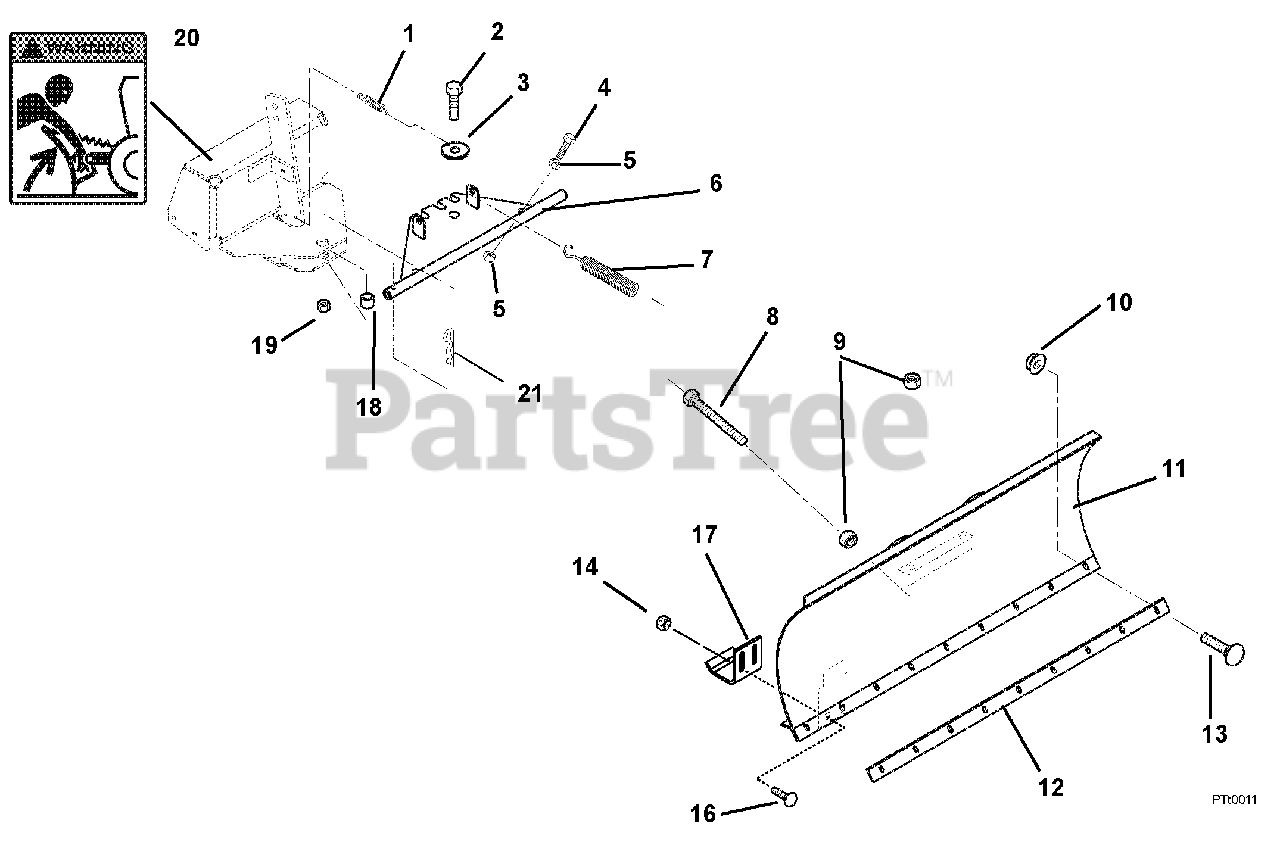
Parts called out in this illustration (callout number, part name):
1	SPRING,LATCH
2	BLT-HEX .75-10X3.00 GR5 YWZC
3	WSHR, SPECIAL
4	@BLT-HEX .50-13X2.00 GR5 YWZC
5	@NUT-HEX .50-13 YWZC
6	WMT,PIVOT PLATE
7	SPRING,BLADE ADJUSTMENT
8	BLT,HEX 3/8-16X4.00 FULL TH'D
9	@NUT-HEX .38-16 YWZC
10	@NUT-LK-TOP-FLG .31-18 YWZC
11	DOZER BLADE, 54" WELDMENT 12GA
12	SCRAPER BLADE, 54" DOZER BLADE
13	@BLT-RDHDSQNK .31-18X.75 G5YZ
14	@NUT-LK-CTR .38-16 YWZC
16	@BLT-RDHDSHSQNK.38-16X1.0 G5YZ
17	SKID SHOE
18	SPACER, .753X1.00X1.60
19	NUT-LK-JAM-NYL .75-10 YWZC
20	DECAL, PINCH POINT
21	PIN-HAIR-INT .15X2.937 YWZC
